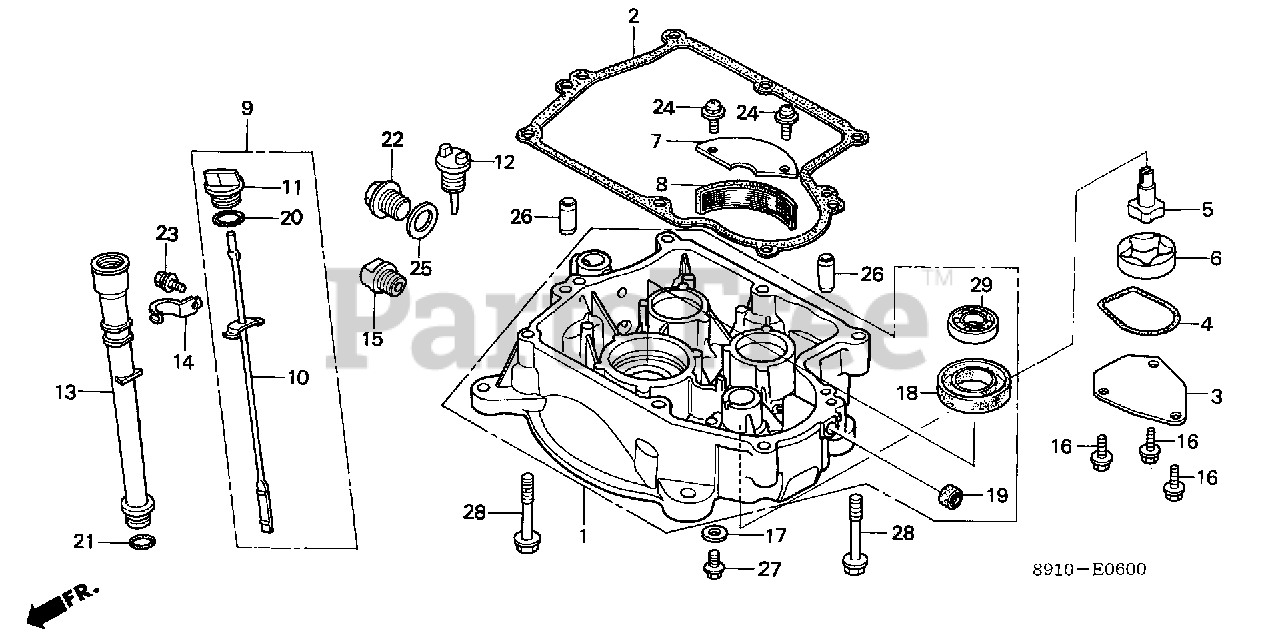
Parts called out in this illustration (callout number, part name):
1	PAN ASSY., OIL
2	GASKET, OIL PAN
3	COVER, OIL PUMP (NOT AVAILABLE)
4	O-RING (39X2.9)
5	ROTOR (INNER)
6	ROTOR, OIL PUMP (OUTER)
7	PLATE, OIL FILTER
8	SCREEN, OIL FILTER
16	BOLT, FLANGE (6X12) (CT200)
17	WASHER A (8MM)
18	OIL SEAL (30X46X8)
19	OIL SEAL (6X11X4) (ARAI)
22	BOLT, DRAIN PLUG (20MM)
24	SCREW-WASHER (5X12)
25	WASHER, DRAIN PLUG (20MM)
26	PIN, DOWEL (8X14)
27	BOLT, FLANGE (8X16)
28	BOLT, FLANGE (8X45)
29	BEARING, RADIAL BALL (6206)
